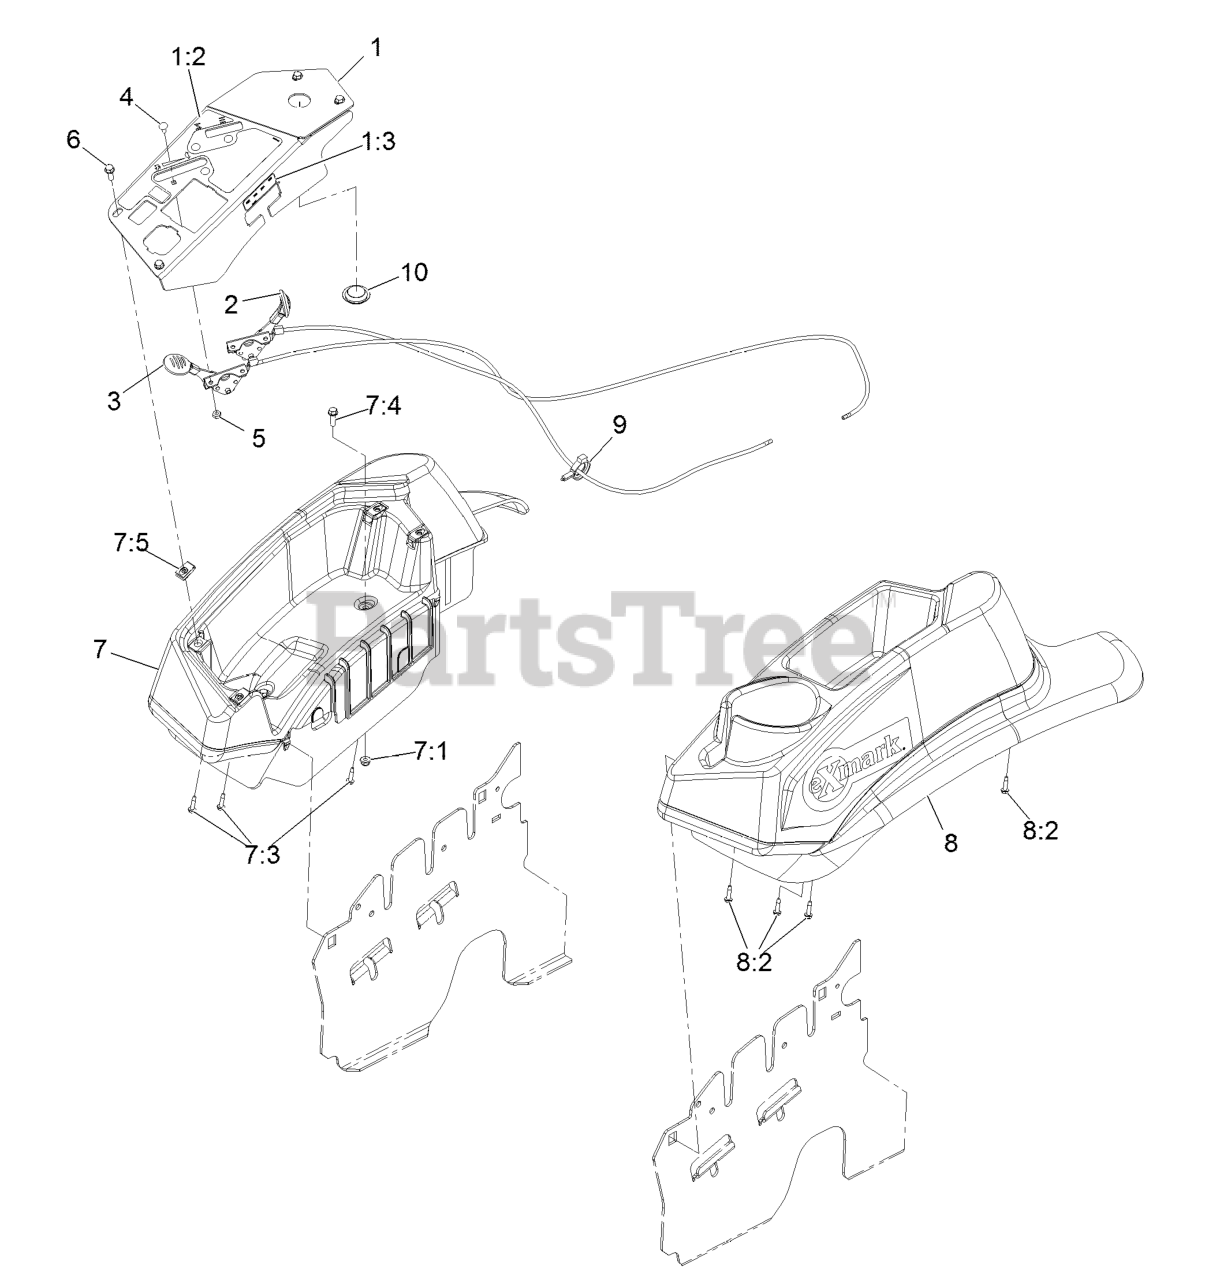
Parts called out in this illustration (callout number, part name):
1	ASM,CONSOLE PANEL W/DECAL
1:2	DECAL-CONTROL PANEL
1:3	DECAL-FUSE
2	ASM, CHOKE CABLE
3	ASM,THROTTLE CABLE
4	BOLT-CARR
5	NUT-LOCK, NI
6	SCREW-HWH
7	CONSOLE,RH NARROW ASM
7:3	SCREW,THD FORM,HWH
7:4	SCREW-HWH
7:5	Nut-Retainer-Panel 1/4-20
8	CONSOLE.LH NARROW ASM
8:2	SCREW,THD FORM,HWH
9	CLAMP-HOSE
10	PLUG-PLASTIC
